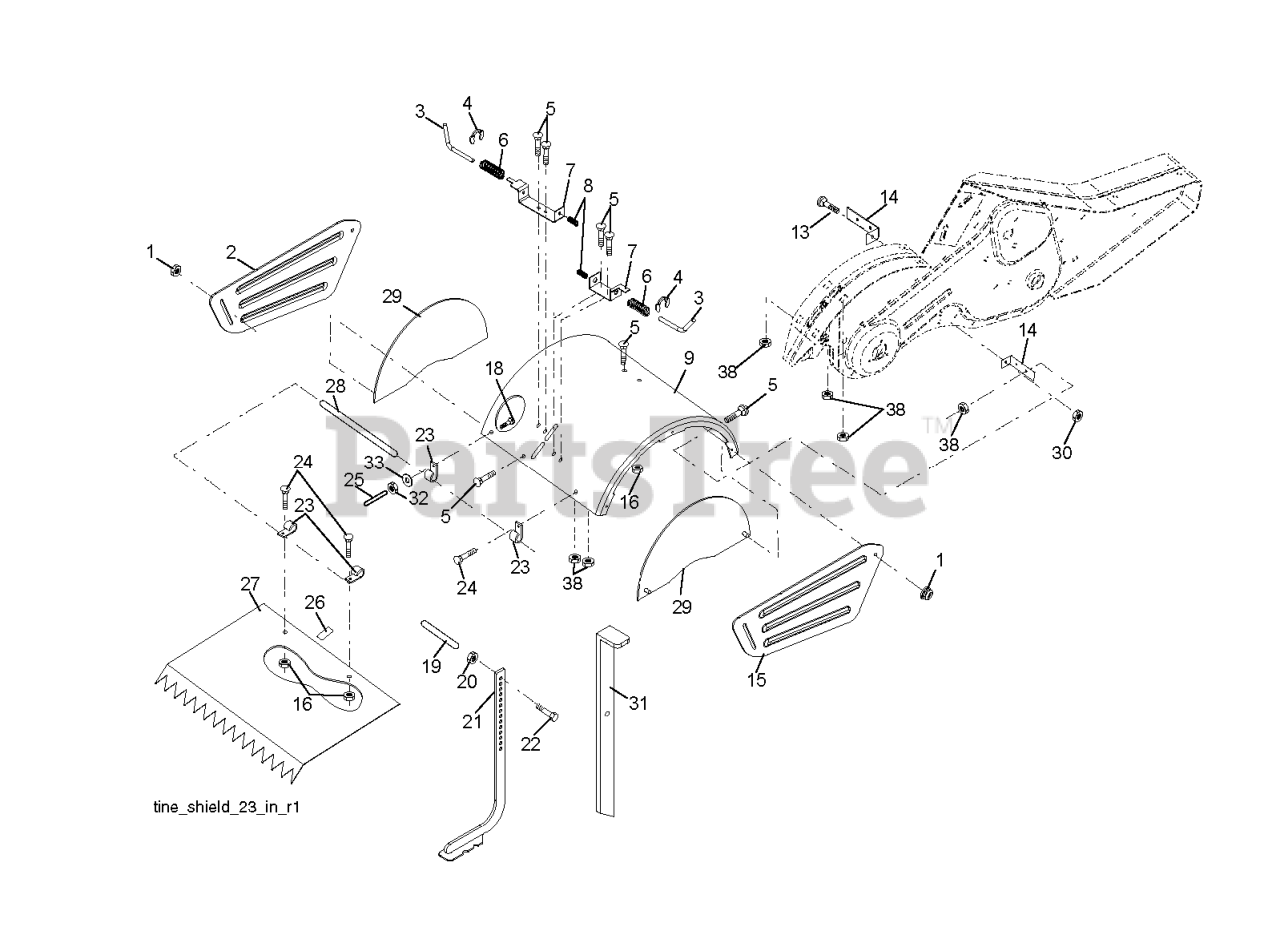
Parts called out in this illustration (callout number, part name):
1	NUT LOCK HEX FLANGE 5/16-18
2	SHIELD.PNT.SIDE.OUTER.LH.ORANG
3	STAKE PIN TI
4	RING, KLIP
5	BOLT, RDHD SQNK 5/16-18 X 3/4
7	BRACKET.LATCH.STAKE.3.20.BLACK
8	SPRING CRT
9	SHIELD.TINE.DRT17.TILLER.ORANG
13	BOLT.CARRIAGE.5/16-18
14	BRACKET.TINE.SHIELD.TILLER
15	SHIELD.SIDE OUTER.RH.ORANGE
16	NUT T
20	NUT.HEX.3/8-16UNC
21	STAKE.DEPTH.16.CRT.BLACK
22	BOLT.375-16
24	BOLT
26	PAD IDLER TI
27	SHIELD.LEVELING.17".ORANGE
28	PIN.HINGE.TILLER
29	SHIELD.TINE.SIDE.ORANGE.TILLER
30	LOCKNUT-FLANGE 5/16-18
31	STAKE, DRAG
32	NUT
33	LOCKWASHER
38	NUT
